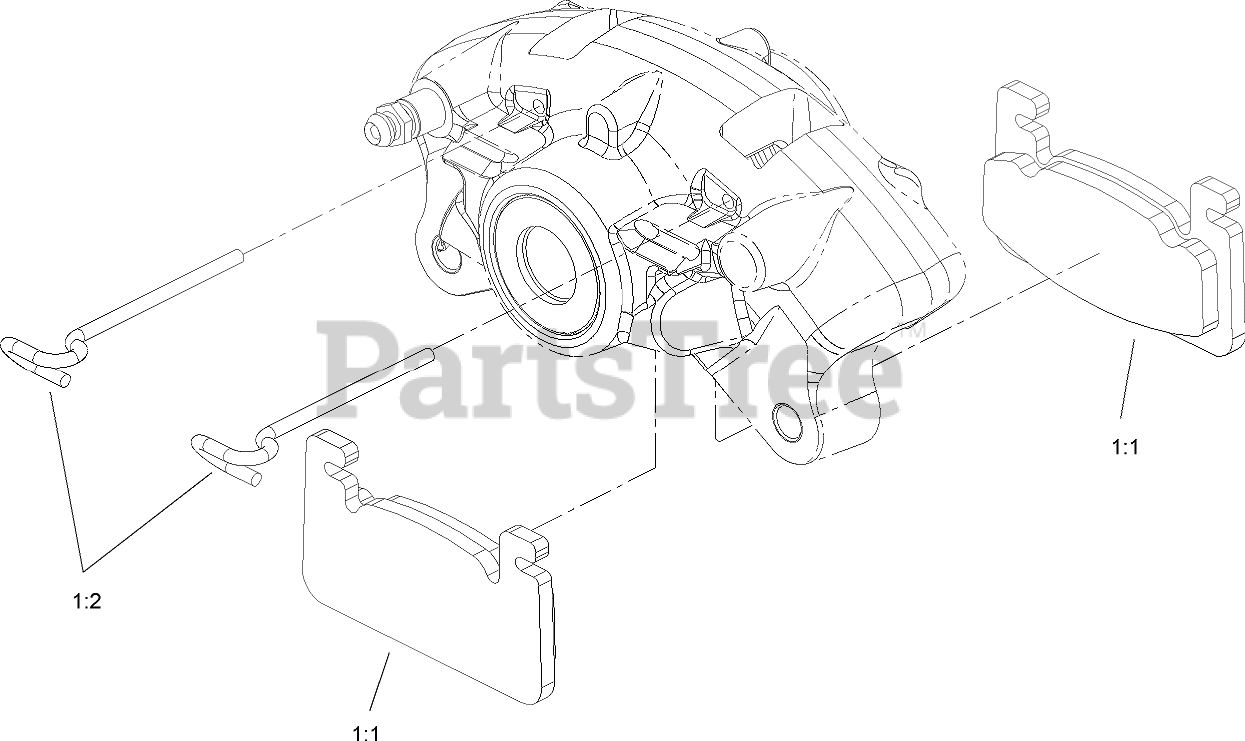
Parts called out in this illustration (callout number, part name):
1	FRICTION PAD AND PIN KIT
1:1	BRAKE PAD ASM
1:2	Pin
